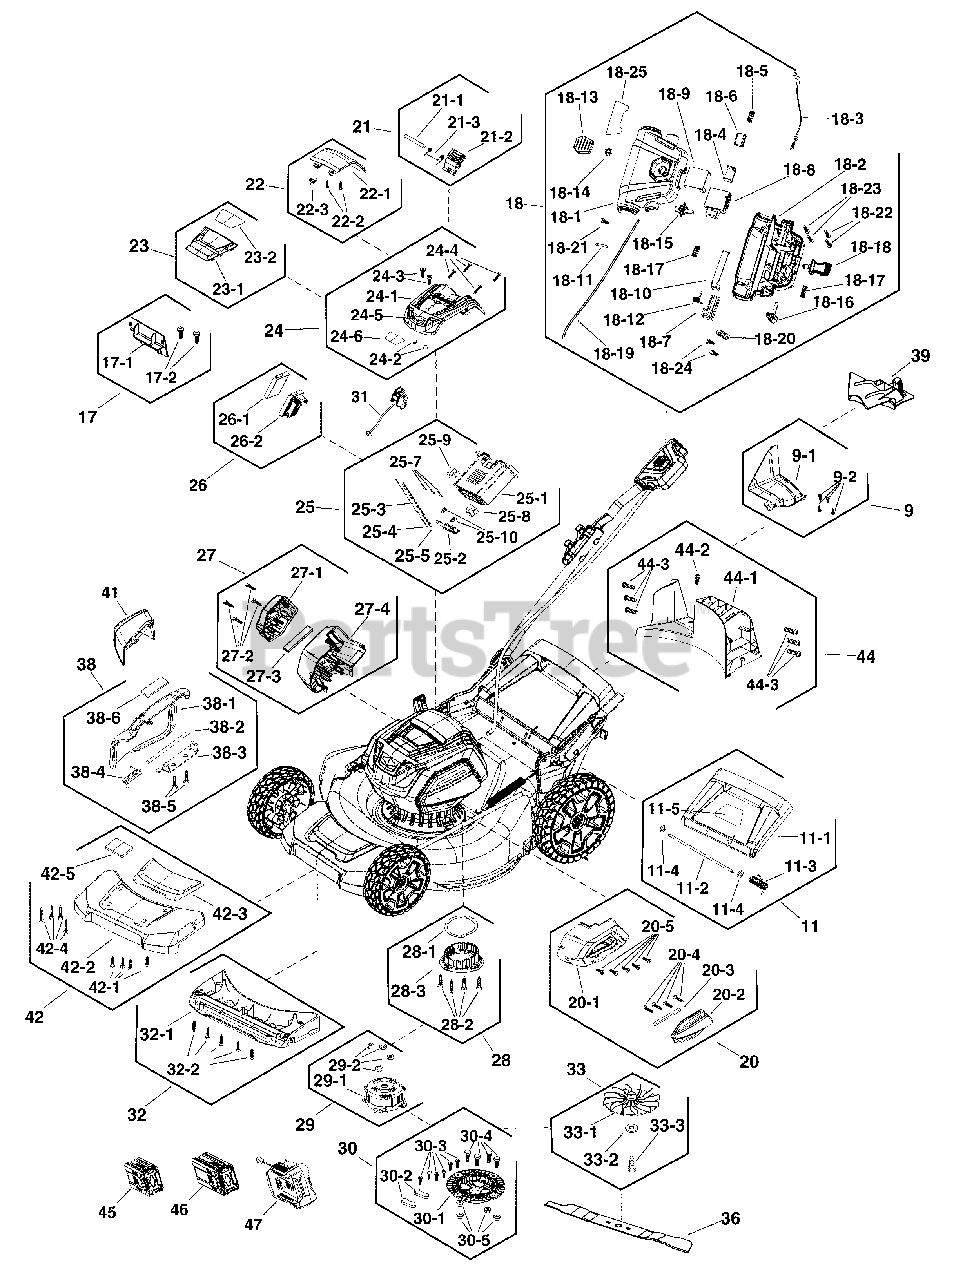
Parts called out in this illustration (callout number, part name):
9	KIT, Transition
9-1	CASING
11	KIT, Rear Cover
11-1	COVER, Rear
11-2	PIN
11-3	SPRING
11-4	WASHER, Split
11-5	DECAL, Warning
17	KIT, Cover
17-1	COVER, PCB
18	KIT, Start Button
18-1	COVER, Upper
18-2	COVER, Bottom
18-3	CABLE, Bail
18-4	SLIDER
18-5	SPRING
18-6	SEAT, Fixed
18-7	SLIDER
18-9	INSERT
18-10	PLATE
18-11	PIN
18-12	SPRING
18-13	BUTTON, Start
18-14	SPRING
18-15	GASKET
18-16	LOCK
18-17	SPRING
18-18	SEAT, Fixed
18-19	HARNESS
18-20	CLAMP
18-25	DECAL
20	KIT, Left Cover
20-1	COVER, Left
20-2	HOUSING, Left
20-3	SCREEN, Dust
21	KIT, Battery Release
21-1	PIN
21-2	BUTTON
21-3	SPRING
22	KIT, Battery Cover
22-1	COVER, Battery
22-3	SPRING
23	KIT, Cover
23-1	COVER
23-2	SHROUD
24	KIT, Top Cover
24-1	COVER, Top
24-2	MAGNET
24-3	LABEL
24-5	B&S LOGO
24-6	LABEL
25	KIT, Battery Compartment
25-1	HOUSING, Battery
25-2	TERMINAL
25-3	WIRE, Red
25-4	WIRE, Yellow
25-5	WIRE, Black
25-7	CONTACT
25-8	CONNECTOR
25-10	SPRING
26	KIT, PCB
26-1	COVER, PCB
26-2	PCB
27	KIT, Cover, Right
27-1	COVER, Right
27-3	SCREEN, Dust
27-4	COVER, Right
28	KIT, Base
28-1	BASE
28-3	BASE
29	KIT, Motor
29-1	MOTOR
29-2	NUT
30	KIT, Motor Base
30-1	BASE
30-2	DISC, Tension
30-4	BOLT
30-5	NUT
31	KIT, Inverted Switch
32	KIT, Front Bulkhead
32-1	BAFFLE, Front
33	KIT, Fan
33-1	FAN
33-2	WASHER
38	KIT, Discharge Chute
38-1	COVER
38-2	PIN
38-3	BRACKET
38-4	SPRING, Torsion
38-6	DECAL, Side Discharge
39	KIT, Mulching Plug
41	KIT, Discharge Chute
42	KIT, Front Panel
42-2	PANEL
42-3	COVER, Panel
42-5	DECAL
44	KIT, Rear Baffle
44-1	BAFFLE, Rear
45	* BATTERY, 2.0, 82V EU/AU
46	* CHARGER, Battery, EU
47	* BATTERY, 4.0, 82V EU/AU
